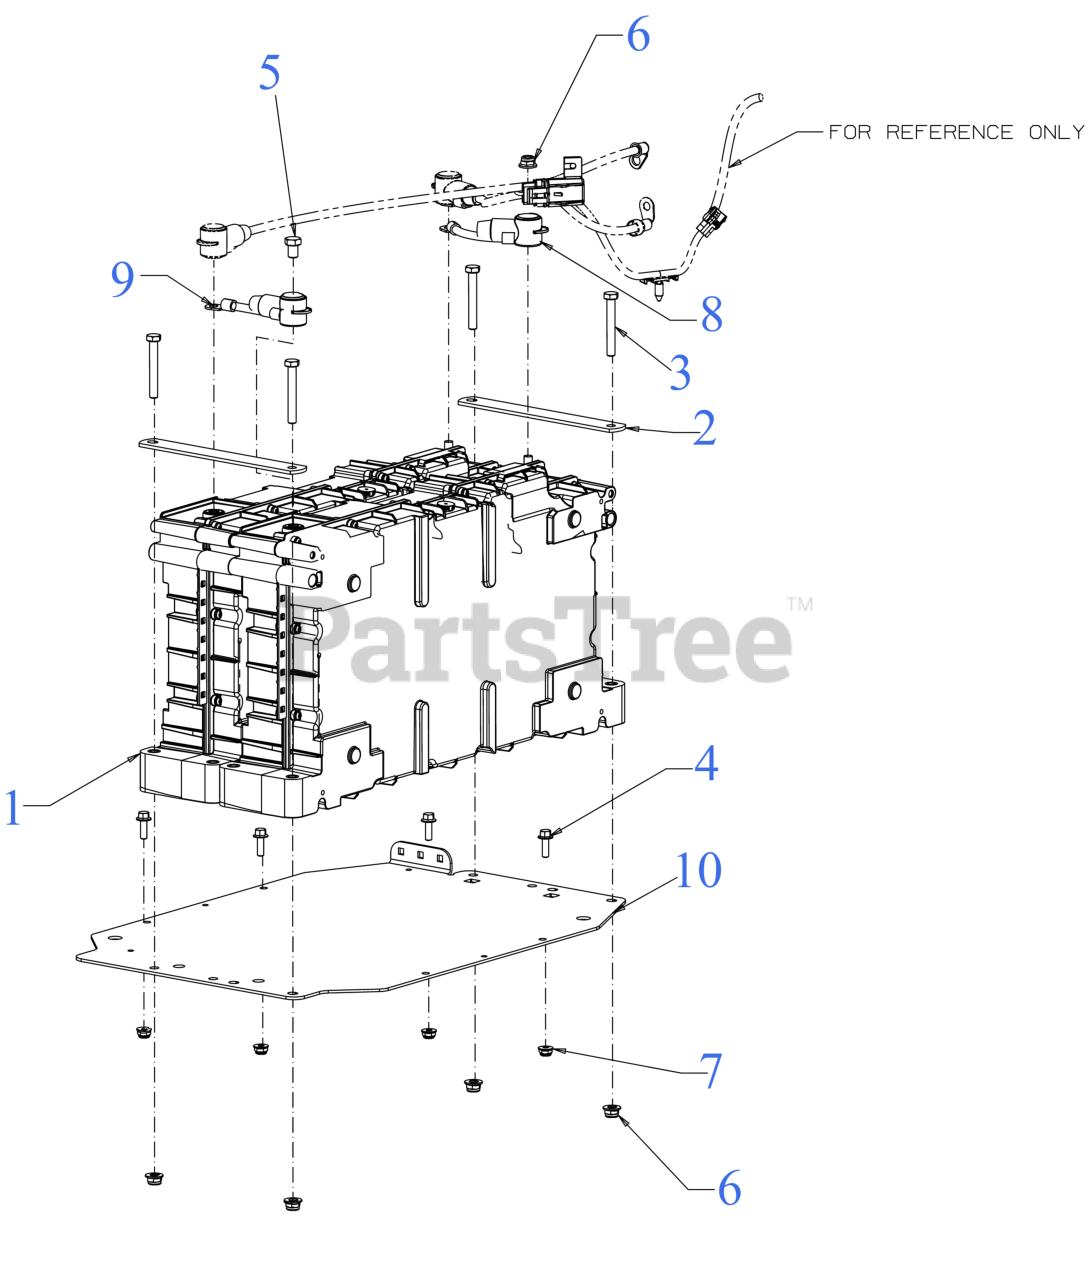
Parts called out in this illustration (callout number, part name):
2	BATTERY MOUNTING PLATE
3	HEX SCREW 5/16-18 x 2.25 GR5
4	SCREW 1/4-20 x .75 GR5
5	SCREW 3/8-24 x .50" GR5 STD
6	FLANGE LOCK NUT 5/16-18
7	FLANGE LOCK NUT
8	JUMPER BATTERY HARNESS
9	JUMPER BATTERY HARNESS
10	BATTERY PLATE BRACKET
